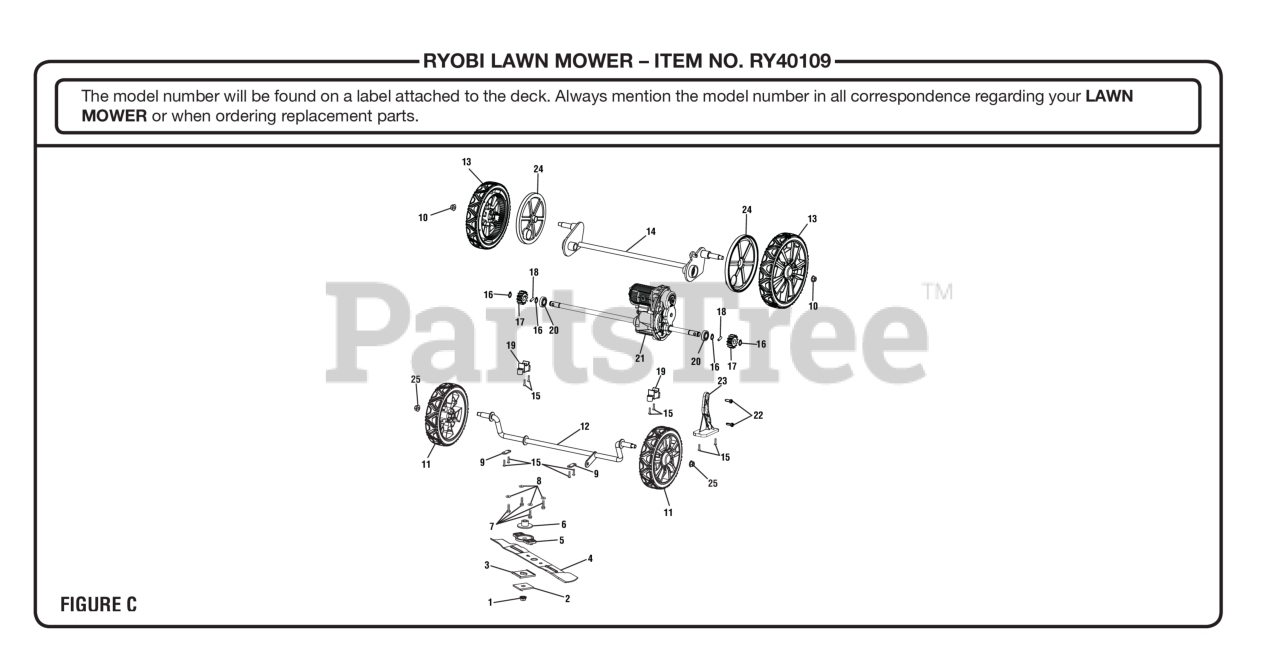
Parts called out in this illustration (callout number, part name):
1	Blade Nut (M10 x 1.25, Hex Flange Hd.)
2	Metal Blade Retainer
4	Bagging Blade
5	Blade Holder
6	Motor Shaft Bushing
7	Bolt (M6 x 26 mm, Hex Hd.)
8	Washer (ID6.2 x OD15 x 0.08t)
9	Axle Pressure Plate
10	Lock Nut (3/8-16, Flange)
11	8 in. Wheel Assembly
12	Front Axle
13	Rear Wheel Assembly
14	Rear Wheel Axle with rotation Plate
15	Screw (M4 x 20 mm, T20 Torx Pan Hd. S.T.)
16	Retaining Ring
17	Drive Gear
18	Gear Shaft
19	Mounting Plate
20	Ball Bearing (OD28.6 x ID12.7 x 8)
21	Transmission Assembly
22	Screw (T20 x 12 mm)
23	Transmission Holder
24	Wheel Cover
25	Flange Lock Nut (M8 x 1.25 mm)
